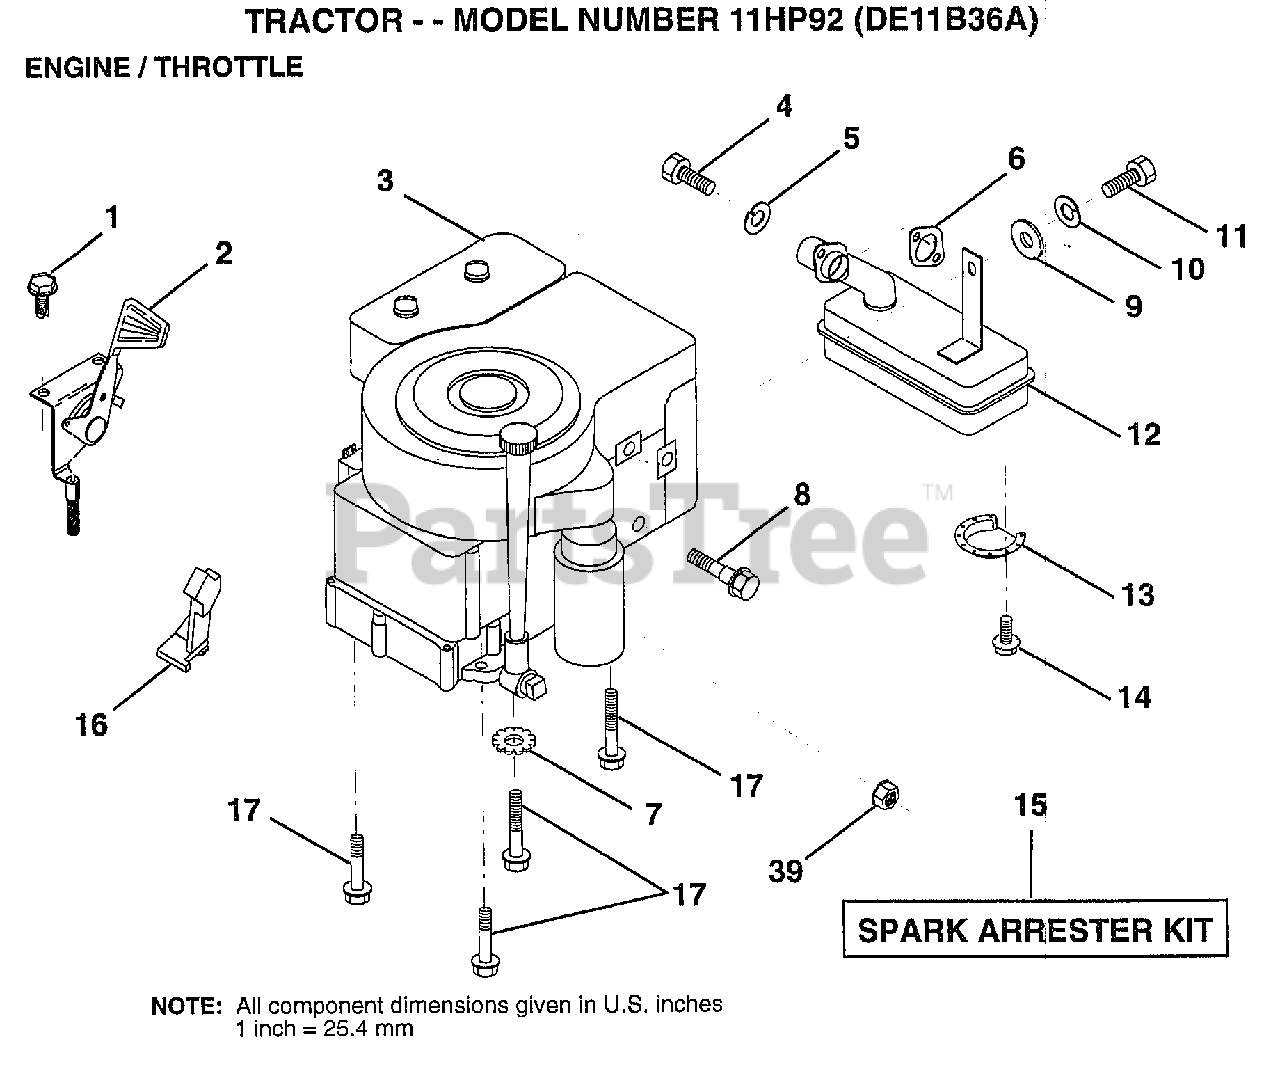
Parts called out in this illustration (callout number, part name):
1	SCREW LT
4	SCREW
5	LOCKWASHER
7	LOCKWASHER
8	BOLT T
10	LOCKWASHER
12	MUFFLER
13	DEFLECTOR.222573
16	"STOP,DASH THROTT"
17	SCREW LT
39	NUT
